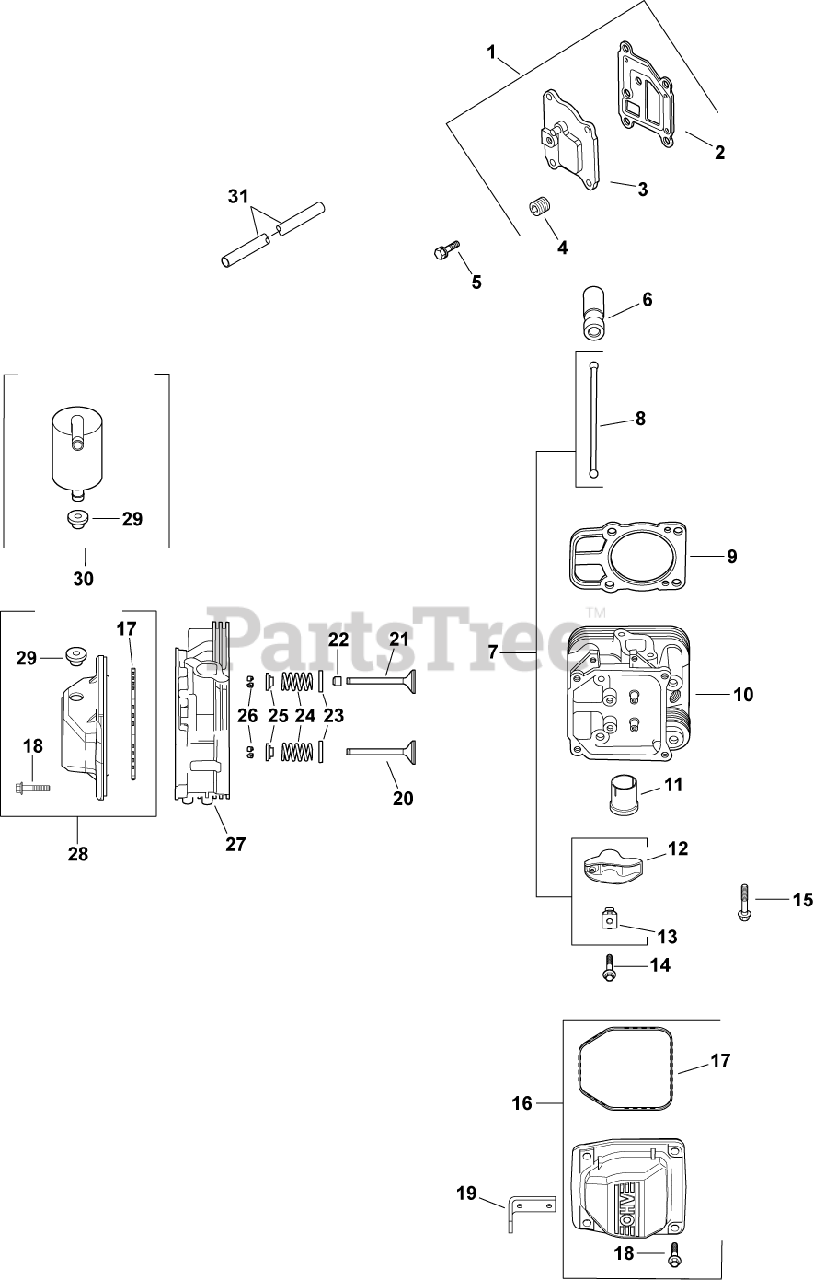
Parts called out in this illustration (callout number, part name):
1	KIT, BREATHER COVER W/GASKET
2	GASKET, BREATHER-USE 24 041 67-S
3	COVER, BREATHER -USE 24 096 125-S
4	PLUG, CTSK PIPE 1/8"
5	SCREW,FLG THD FRM M6X1.0X20-(#25086396S)
6	LIFTER, HYDRAULIC VALVE-USE 25 351 10-S
7	KIT, VALVE TRAIN
8	ROD, PUSH
9	KIT, CYLINDER HEAD GASKET
10	HEAD, ASSEM CYLINDER #2 -USE 24 318 116-
11	LINER, EXHAUST PORT-USE 24 605 07-S
12	PIVOT, ROCKER ARM
13	ARM, ROCKER
14	SCREW, FLG M6X1.0X34
15	SCREW - USE 62 086 08-S
16	KIT, VALVE COVER-PLAIN
17	O-RING (YELLOW), VALVE COVER
18	SCREW, FLG M6X1.0X30
19	STRAP, LIFTING-USE 25 445 03-S
20	VALVE, EXHAUST (STD) - USE 32 016 01-S
21	VALVE, INTAKE (STD)
22	SEAL, VALVE STEM - (#2503214S)
23	RETAINER, SPRING
24	SPRING, VALVE
25	RETAINER, VALVE SPRING - USE 25 173 28-S
26	KIT, RETAINER
27	HEAD, ASSEM CYLINDER #1 -USE 24 318 108-
28	KIT, VALVE COVER
29	GROMMET, RUBBER
30	KIT, BREATHR SEPARATR-(#24755241S)
31	HOSE, BREATHER
2401602-S	VALVE, EXHAUST (.25)
2401702-S	VALVE, INTAKE (.25)
24755147-S	KIT, CYLINDER HEAD HARDWARE
